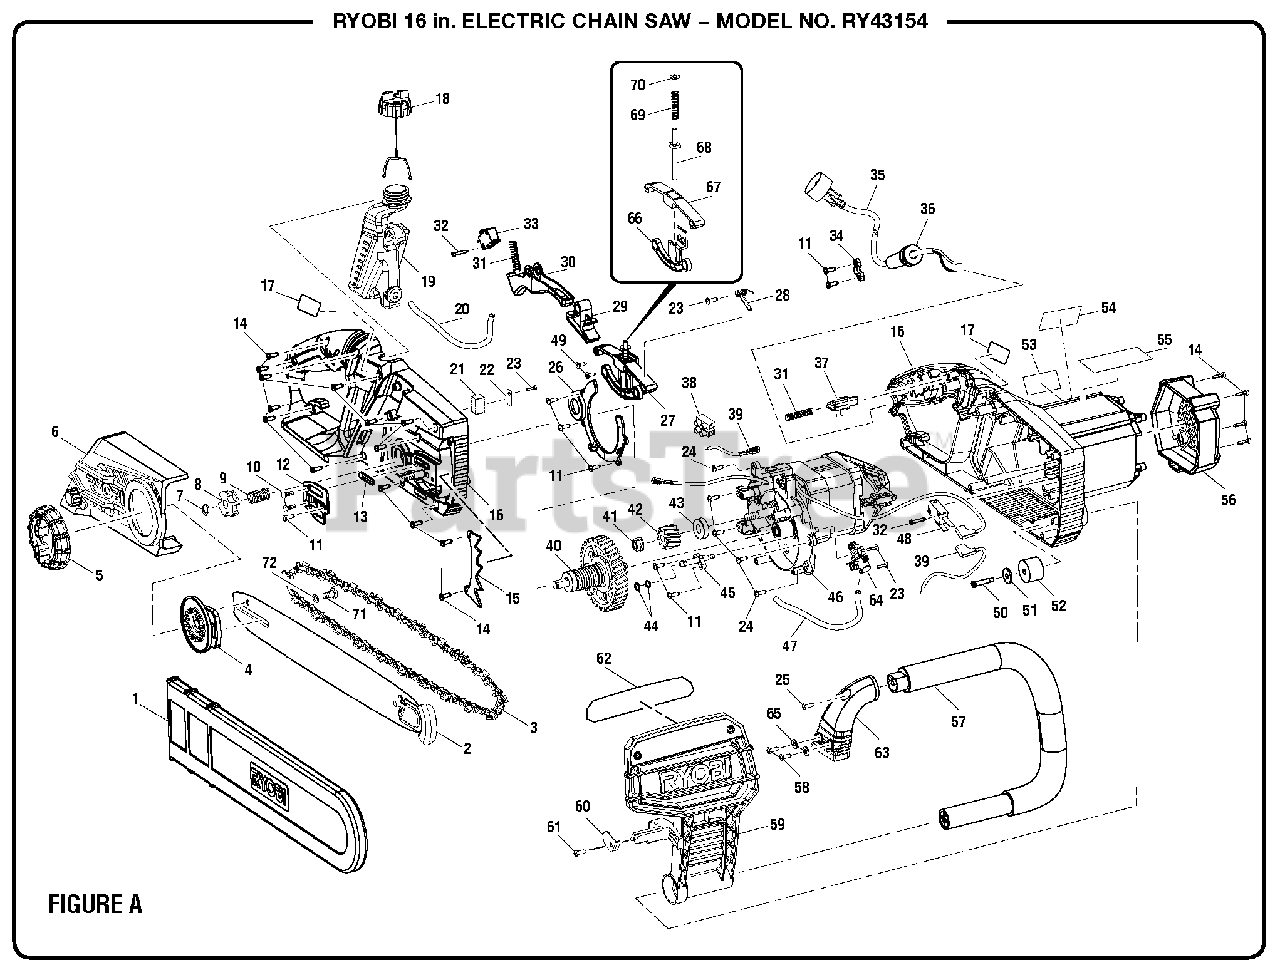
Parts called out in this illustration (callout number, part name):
3	Chain (16 in.)
4	Chain Tensioner Assembly
5	Chain Adjusting Knob Assembly
6	Bar Cover Assembly
8	Chain Sprocket
12	Guide Plate
16	Housing Assembly
17	Side Logo Label
18	Oil Tank Cap Assembly
19	Oil Tank Assembly
26	Dust Shield
27	Brake Assembly
28	Brake Spring
29	Intermediate Connecting Rod
36	Cord Sheath
37	Lock-Off Button
38	Terminal Connector
39	Stator Wire
40	Output Shaft Gear Assembly
43	Motor Gear Bushing
45	Nozzle Assembly
46	Motor Assembly
47	Oil Tube With Spring
48	Control Switch
53	Danger/Warning Label
54	Warning/Data Label
55	Icon/Danger Label
56	Motor Cover
57	Front Handle
59	Front Handle Guard
60	Handle Guard Plate
62	Chain Brake Label
63	Front Handle-Right
64	Oil Pump Assembly
66	Brake Bar Plate
67	Link Switch
69	Brake Lever Spring
71	Tension Screw
